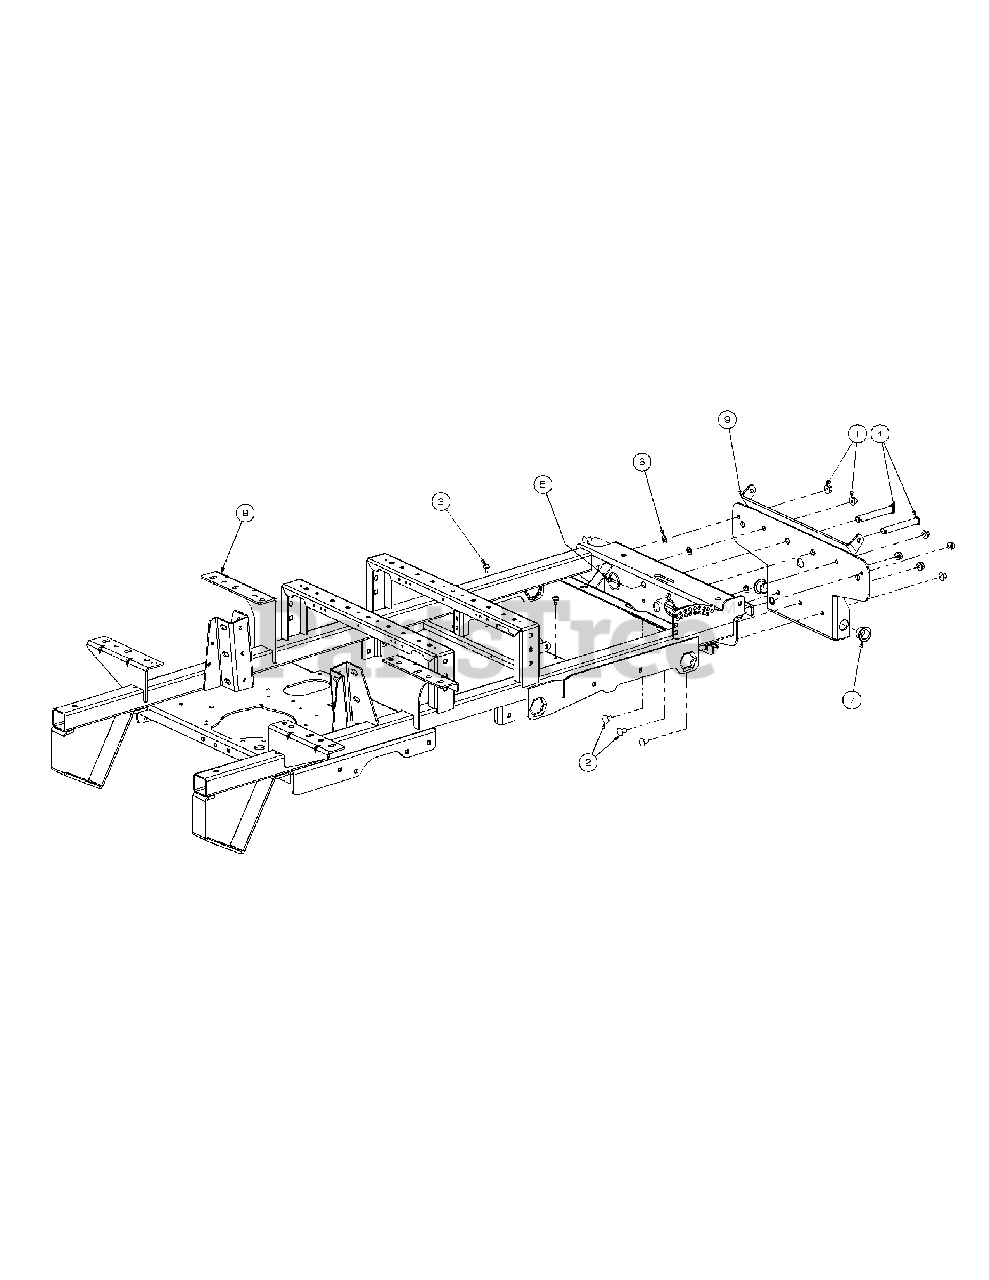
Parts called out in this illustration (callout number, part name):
1	Hex Nut, 3/8-16 Flange Lock
2	Carriage Bolt, 3/8-16 x .75 Long
3	Rubber Bumper, .62 OD x .22 Thick
4	Clevis Pin, .625 Dia x 4.375 Long
5	Hitch Pin, .120 Dia x 3.0
6	Push Retainer, 3/8
7	Bronze Bushing, 1.00 ID x 1.50 OD
8	Frame Assembly
9	Bracket Assembly, Frame, Front
